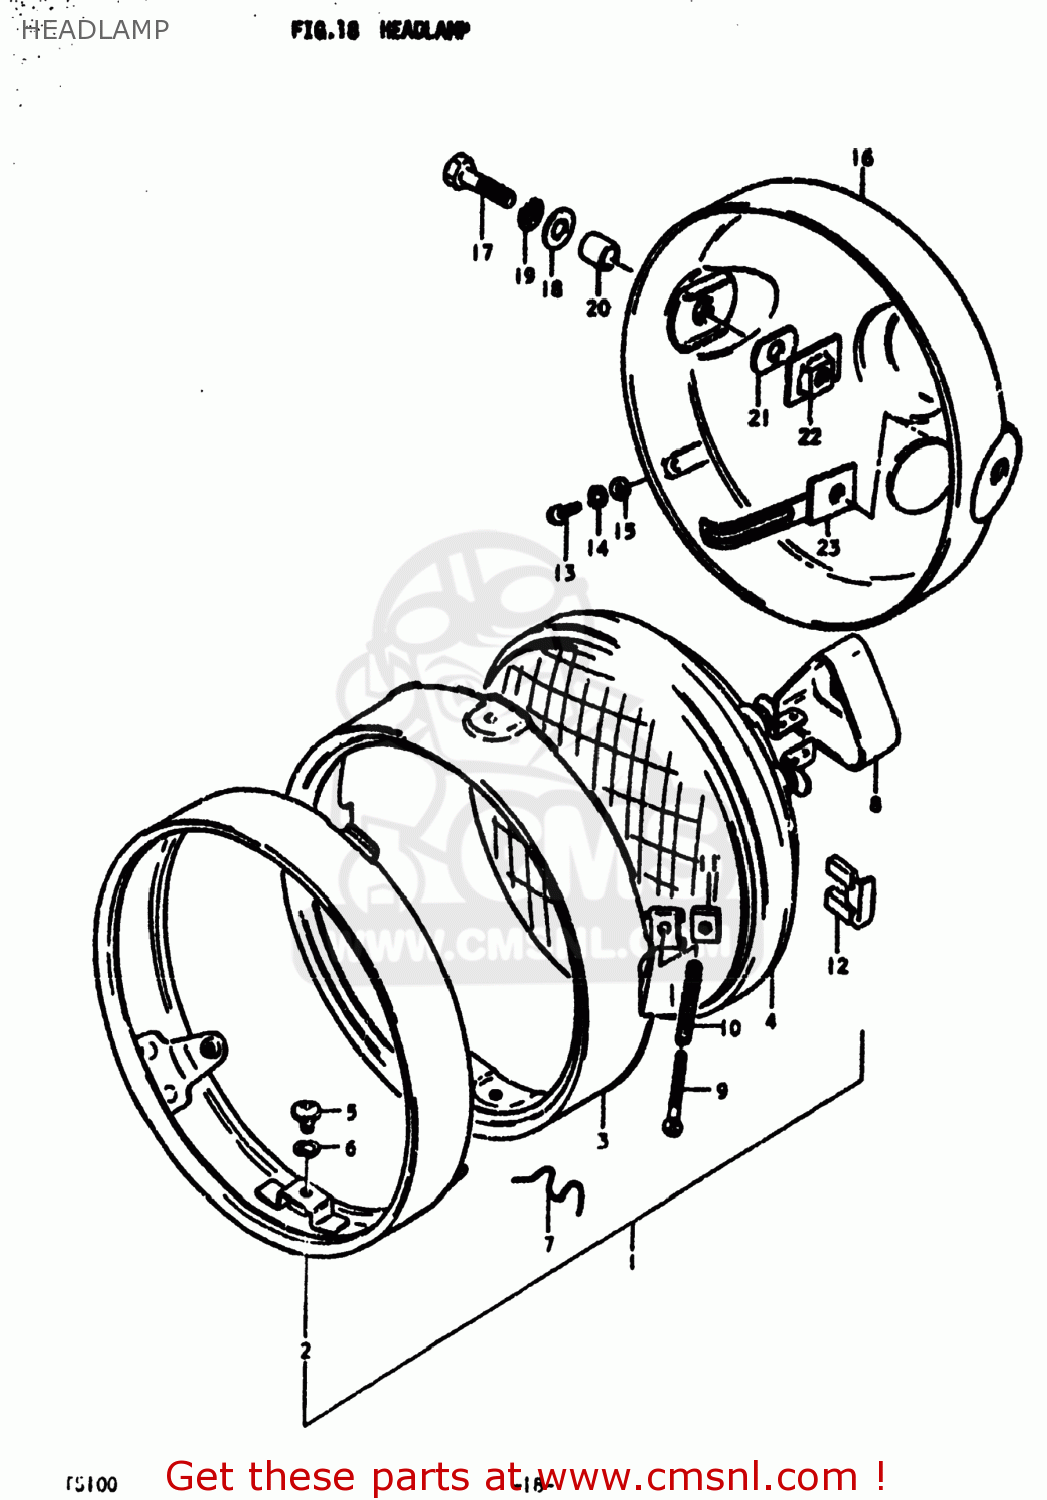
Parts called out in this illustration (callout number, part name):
1	LAMP ASSEMBLY,HEAD
2	RIM,HEADLAMP
3	RETAINER
4	LAMP UNIT
5	SCREW
6	LOCK WASHER
7	SPRING,HEAD LAMP UNIT
8	COVER
9	SCREW
10	SPRING,HEADLAMP ADJUST
11	NUT
12	COVER, FITING
13	SCREW
14	LOCK WASHER
15	WASHER
16	HOUSING,HEADLAMP
17	BOLT
18	WASHER
19	LOCK WASHER
20	SPACER (8.8X12X7)
21	CUSHION
22	PLATE,HEADLAMP HOUSING
